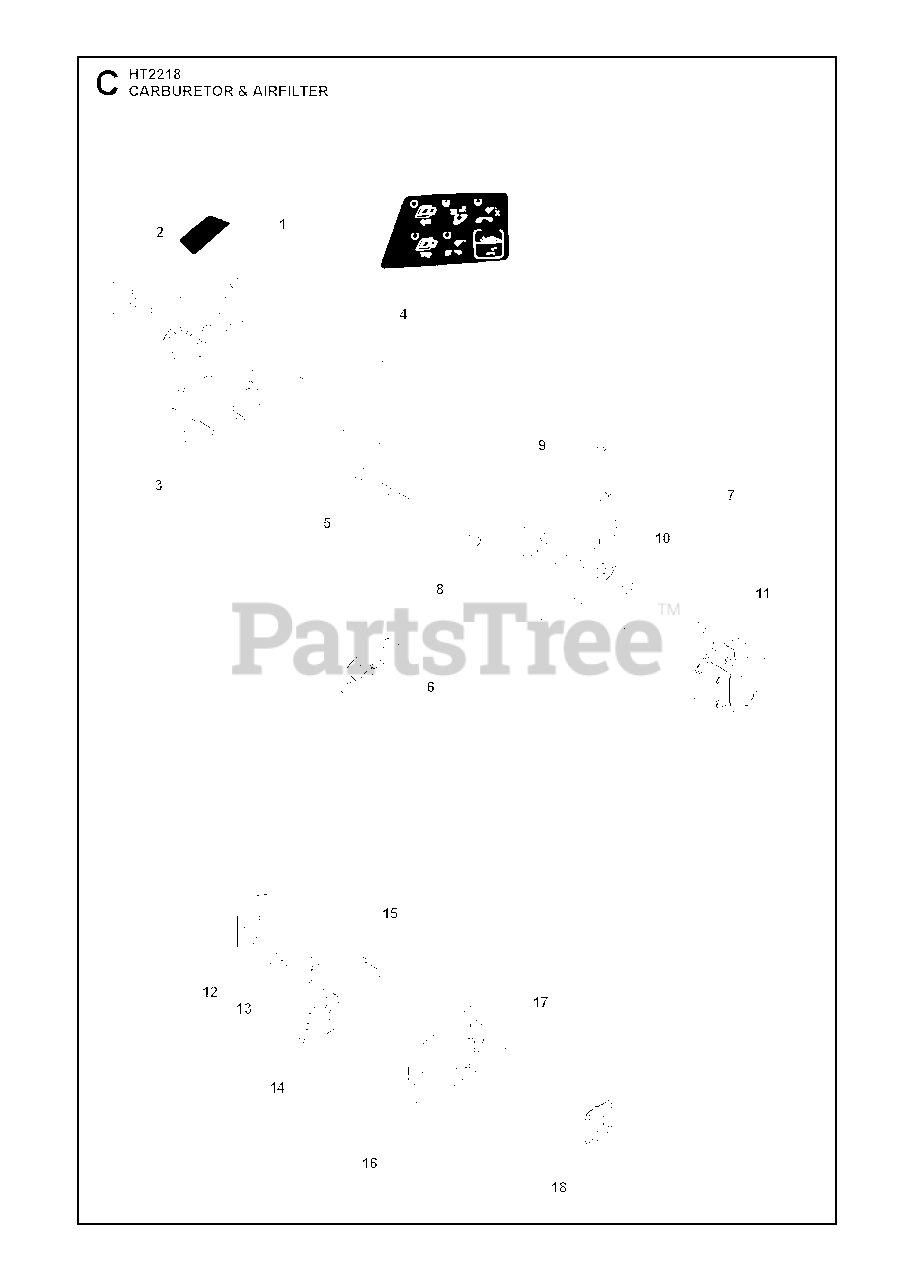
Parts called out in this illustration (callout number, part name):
4	AIR FILTER
7	FILTER HOLDER ASSY
8	RIVET TUBULAR
9	RIVET TUBULAR
10	NUT
11	CARBURETOR ASSY.
17	TUBULAR RIVET
